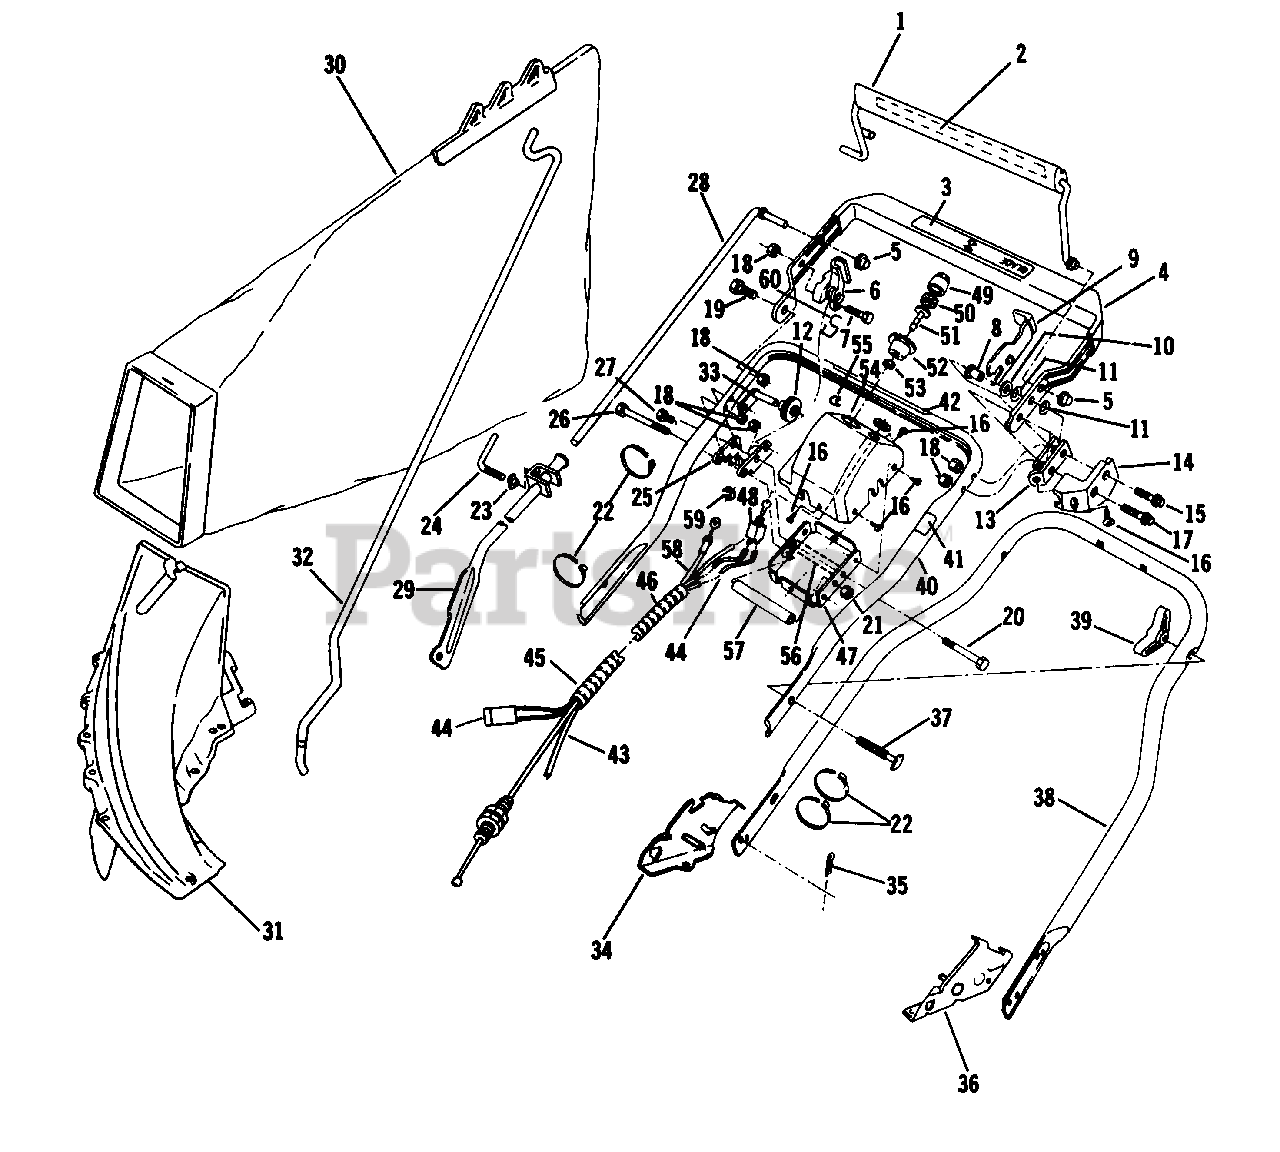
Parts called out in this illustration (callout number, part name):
1	Control Lever Assembly-Bail
2	Decal-Blade Control
3	Decal-Drive Control
4	Top Handle and Grip Assembly
5	Pushnut
6	Cam-Cluth Cont. Bail
7	Bolt-Hex
8	Spacer-Flanged
9	Lever-Lockout
10	Washer-Plain
11	Washer-Spring
12	Pulley
13	Down-Stop
14	Guard-Lockout
15	Bolt-Shoulder
16	Screw
17	Bolt-Shoulder-L.H.
18	Locknut
19	Bolt-Shoulder-R.H.
20	Screw-Hex Hd. Cap
21	Nut-Hex Jam
22	Tie Strap
23	Nut-Cont. Lvr. Clamp
24	Lever-Rod Clamp
25	Bracket-Clutch Cable
26	Screw
27	Screw-Clutch Cable Brkt.
28	Rod-Control
29	Control Lever Assembly
30	Bag Assembly
31	Chute Assembly
32	Rod-Grass Bag
33	Pivot-Bracket Pulley
34	Bracket-Handle-R.H.
35	Hair Pin
36	Bracket-Handle-L.H.
37	Screw
38	Handle Section-Bottom
39	Knob
40	Handle Section-Center
41	Decal-Drive Lockout
42	Decal-Starting Inst.
43	Tubing-Primer
44	Wire Harness Assembly
45	Spiral Tubing
46	Spiral Tubing
47	Plate-Cover Assembly
48	Switch Ass'y.
49	Primer Bulb
50	Filter
51	Primer Base
52	Cup
53	Locknut
54	Cover
55	Decal
56	Spacer
57	Spacer
58	Control Cable Assembly
59	Ring-Retainer
60	Retainer-Cable to Cam
